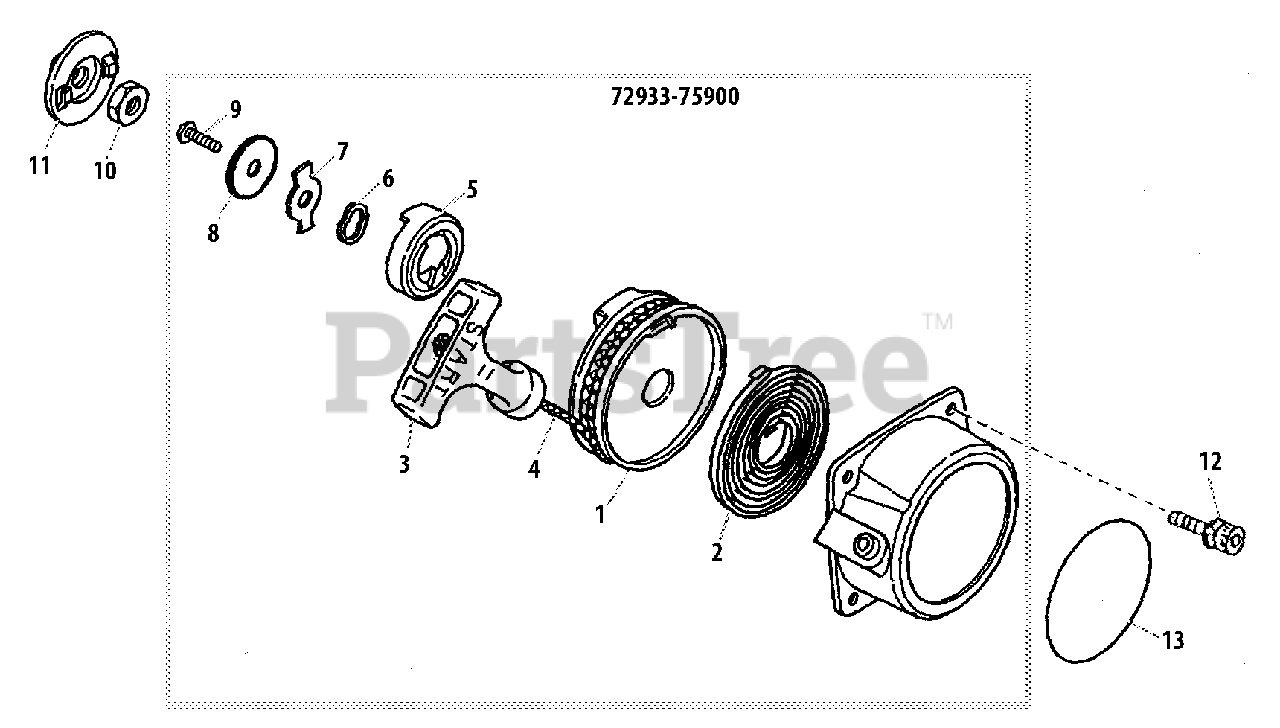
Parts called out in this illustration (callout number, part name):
1	REEL, ROPE
2	SPRING, RECOIL
3	GRIP, STARTER
4	ROPE, STARTER
5	RATCHET
6	WASHER, WAVE
7	RETAINER
8	WASHER 5 MM
9	SCREW 5 MM
10	NUT M8×1
11	PULLEY, STARTER
12	BOLT M4×12
13	LABEL, SHINDAIWA PROFESSIONAL
72933-75900	STARTER ASSY, RECOIL
